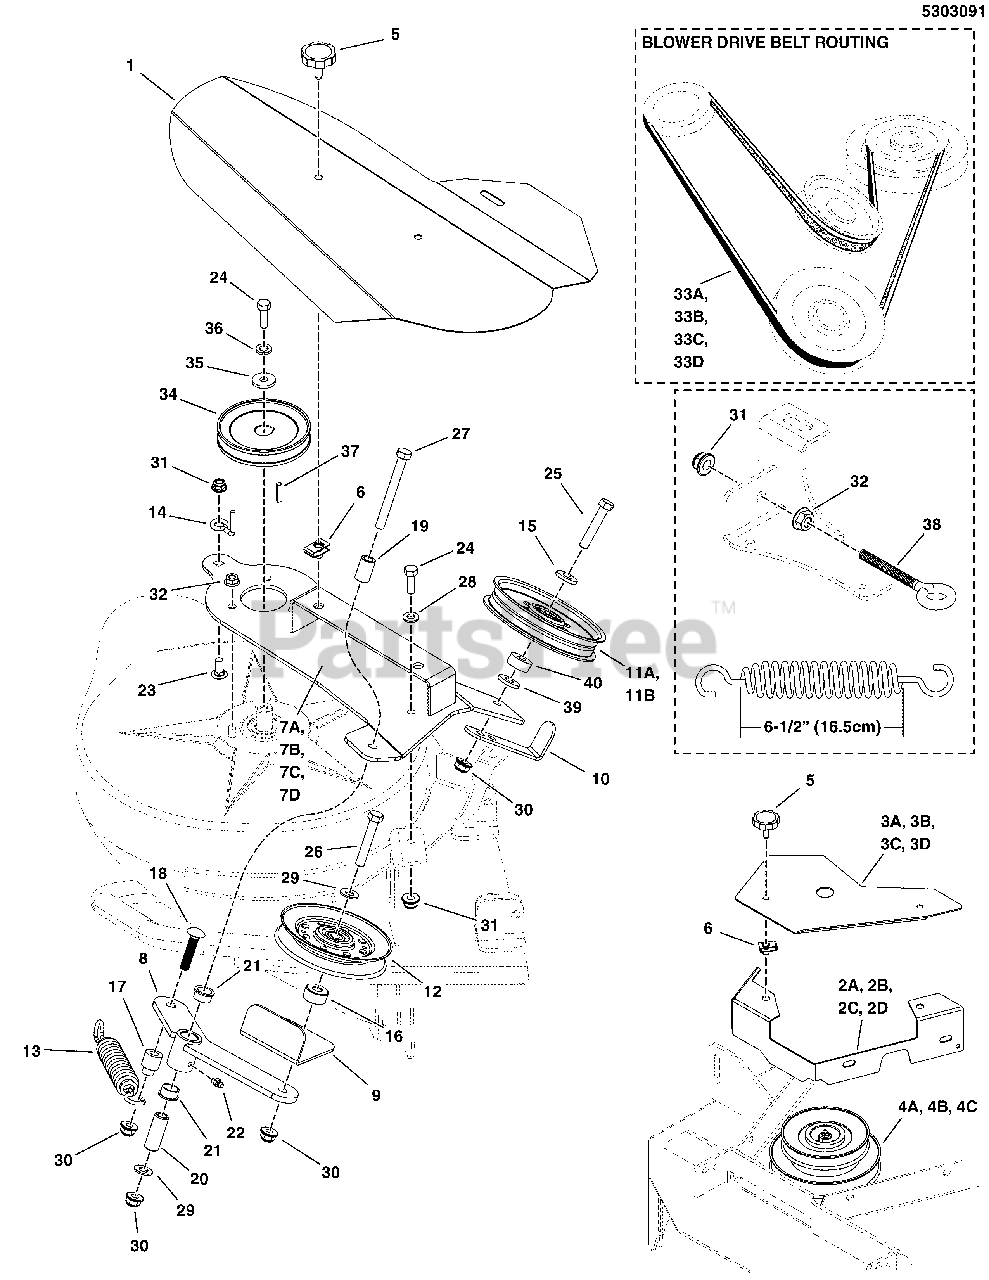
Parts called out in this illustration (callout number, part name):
1	HOOD W/ DECALS - TURBO VAC
5	KNOB, 5/16-18 X 1.00, ROSETTE BLACK
6	NUT, Speed, Lug Type, 5/16-18
8	ASSEMBLY, IDLER ARM - TURBO-VAC
9	RETAINER, BELT, WIDE - BLK
10	RETAINER, BELT
12	PULLEY-IDLER-V, 4.85OB, .38ID
13	SPRING-EXT, 1.04 ODX6.935LGX.148WR, BLK
14	BELT KEEP, .19 X 1.25 - BK
15	WASHER-0.375(0.41IDX1.00ODX.13THK)BLK
16	SPACER, .39 X 1.00 X .50, PM, CZ
17	SPACER,3/8X3/4X15/16
18	BOLT-RD HD SH SQ NK 3/8-16X1.750 G5 BLK
19	SPACER, .39 X .63 X 1.00, YZ
20	SPACER, .38 X .625 X 1.62, YZ
21	BUSHING-0.628IDX0.751ODX0.400LG PWDR MTL
22	GREASE FITTING, 1/4-28 Straight
23	BOLT, 5/16-18 X 3/4, CARRIAGE, GD5, CZ
24	BOLT, 5/16-18 X 1" GRD5 YZ
25	HHCS, 3/8-16 X 2.00, GR5, ZINC/CLEAR
26	BOLT, 3/8-16 X 2-1/4" GD5 CZ
27	BOLT, 3/8-16 X 3-1/2" GD5 CZ
28	WASHER, 5/16" SAE
29	WASHER, 3/8 SAE
30	NUT, 3/8 - 16 HEX NYLOCK FLANGE
31	NUT, 5/16-18 HEX NYLOCK FLANGE NUT
32	NUT, 5/16-18 HEX SERRATED FLANGE (SMALL)
34	PULLEY, 4.3"OB X 3/4"ID, BLOWER
35	WASHER-0.312(0.34IDX1.00ODX.13THK)BLK
36	WASHER, 5/16 LOCK CZ
37	KEY, 3/16" SQ. X 3/4
38	EYE BOLT,5/16-18 X3.5,2.13THRD,.55EYE,CZ
39	WASHER, 3/8" Fender
40	SPACER-0.390ID 0.90 OD 0.34 LG P'MTL YEL
